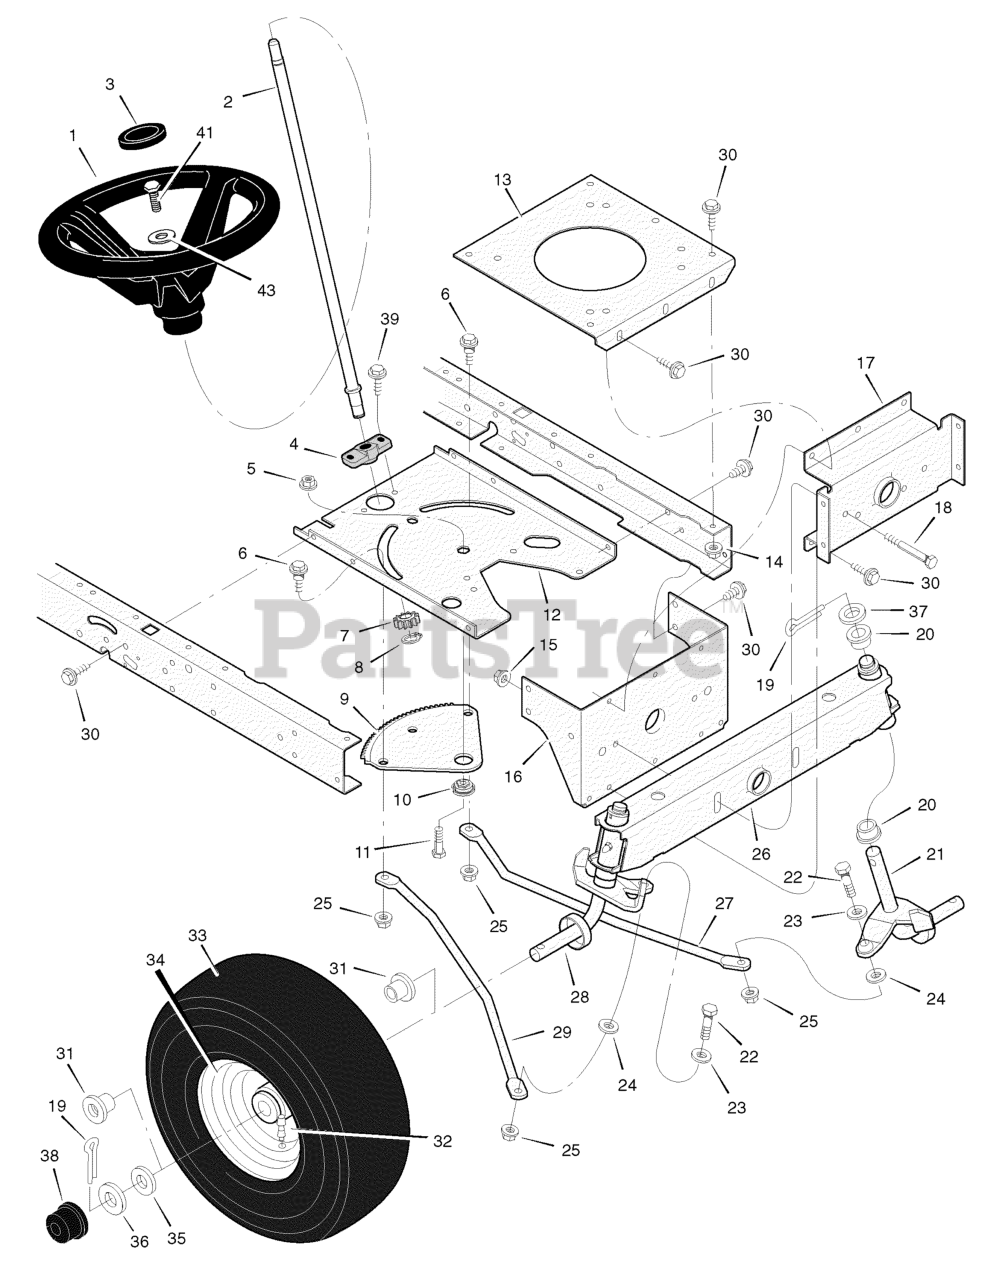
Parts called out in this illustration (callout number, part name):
1	Wheel, Steering
2	Post, Steering
3	Cap, Steering Wheel
4	Bearing
5	Nut, Flange
6	Bolt, Shoulder
7	Gear, Pinion
8	Ring, Snap
9	Gear, Sector
10	Bearing
12	Plate, Steering
13	Plate, Engine
14	Nut, Flange
15	Nut, Flange
16	Bracket, Hanger
17	Axle, Hanger
18	Bolt
19	Pin, Cotter
20	Bearing
21	Spindle Assembly, Left
22	Bolt
23	Washer
24	Washer
25	Nut, Flange
26	Axle Assembly
27	Drag Link, Left
28	Spindle Assembly, Right
29	Drag Link, Right
30	Screw
31	Bearing, Wheel
32	Stem, Valve
33	Tire *
34	Wheel and Tire Assembly
35	Washer
36	Washer
37	Washer
38	Hub Cap
39	Screw
41	Screw, Hex
43	Washer
